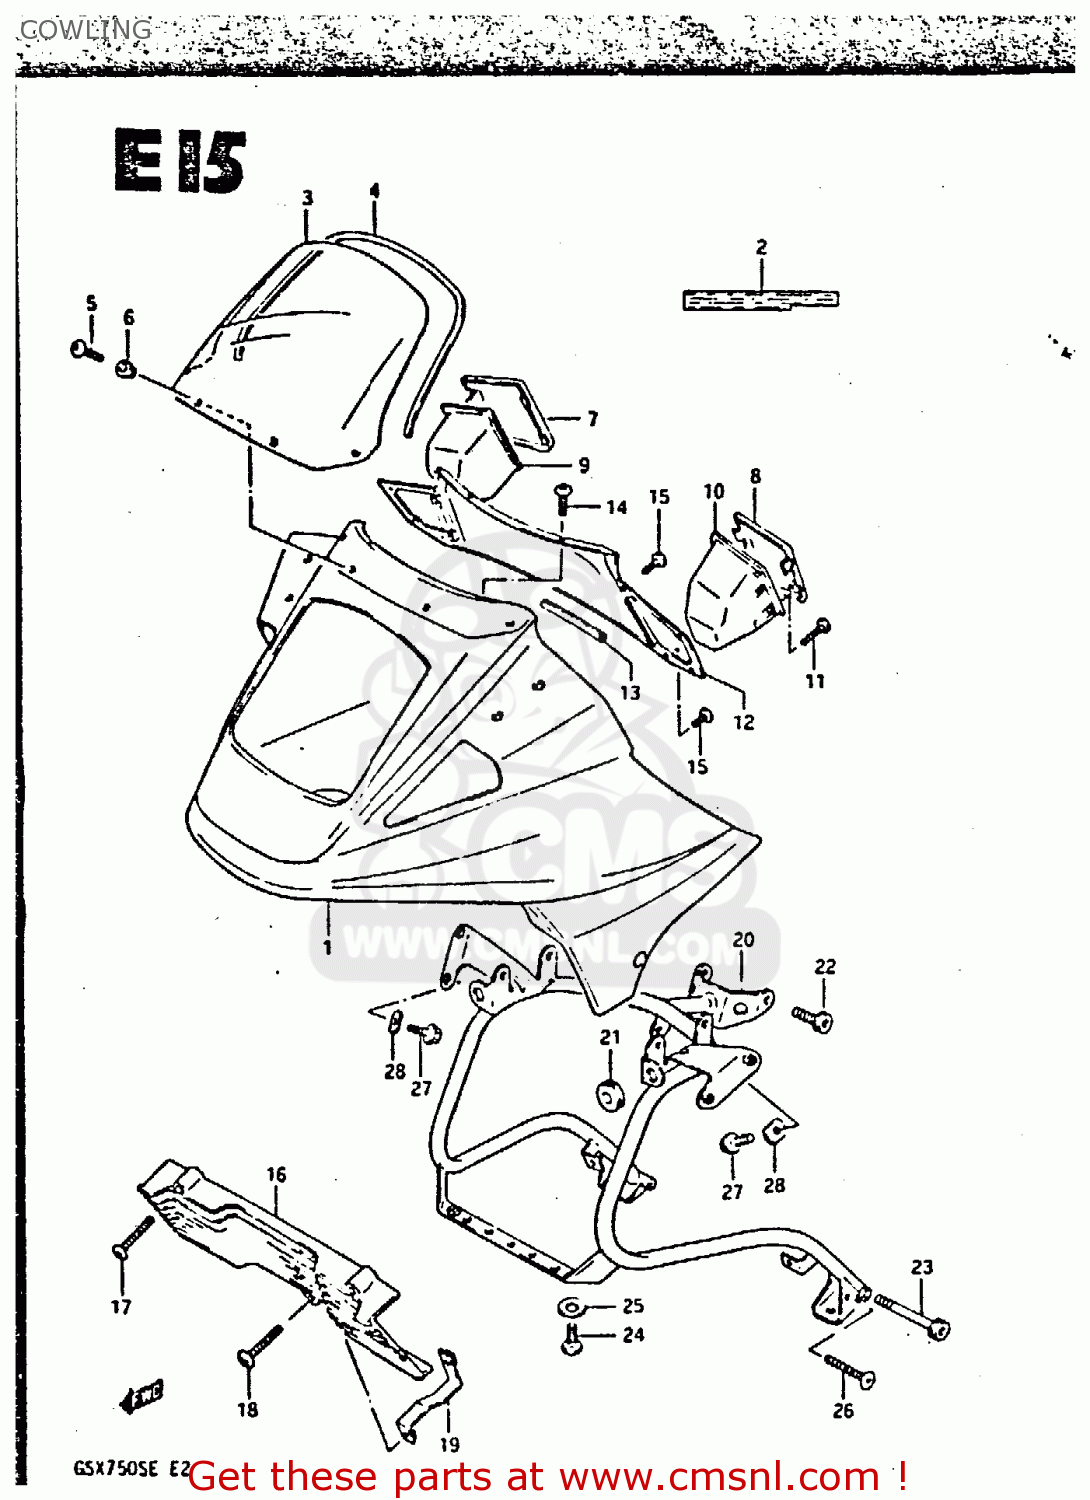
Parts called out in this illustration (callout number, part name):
1	COWLING ASSY
2	LABEL
3	WINDOW,COWLING
4	MOLDING
5	SCREW(5X20)
6	CUSHION
7	COVER,COWLING SIDE BOX,R
8	COVER,COWLING SIDE BOX,L
9	BOX, SIDE RH
10	BOX, SIDE LH
11	SCREW
12	PANEL,UPR
13	CUSHION
14	SCREW M5X12 DIN 7985/N
15	SCREW
16	COVER, OIL COOLER
17	SCREW
18	SCREW, CENTER
19	BRACE, COVER
20	BRACE
21	CUSHION
22	BOLT
23	BOLT, LOWER
24	SCREW
25	WASHER (6.5X20X1.2)
26	SCREW
27	BOLT,REAR
28	NUT
